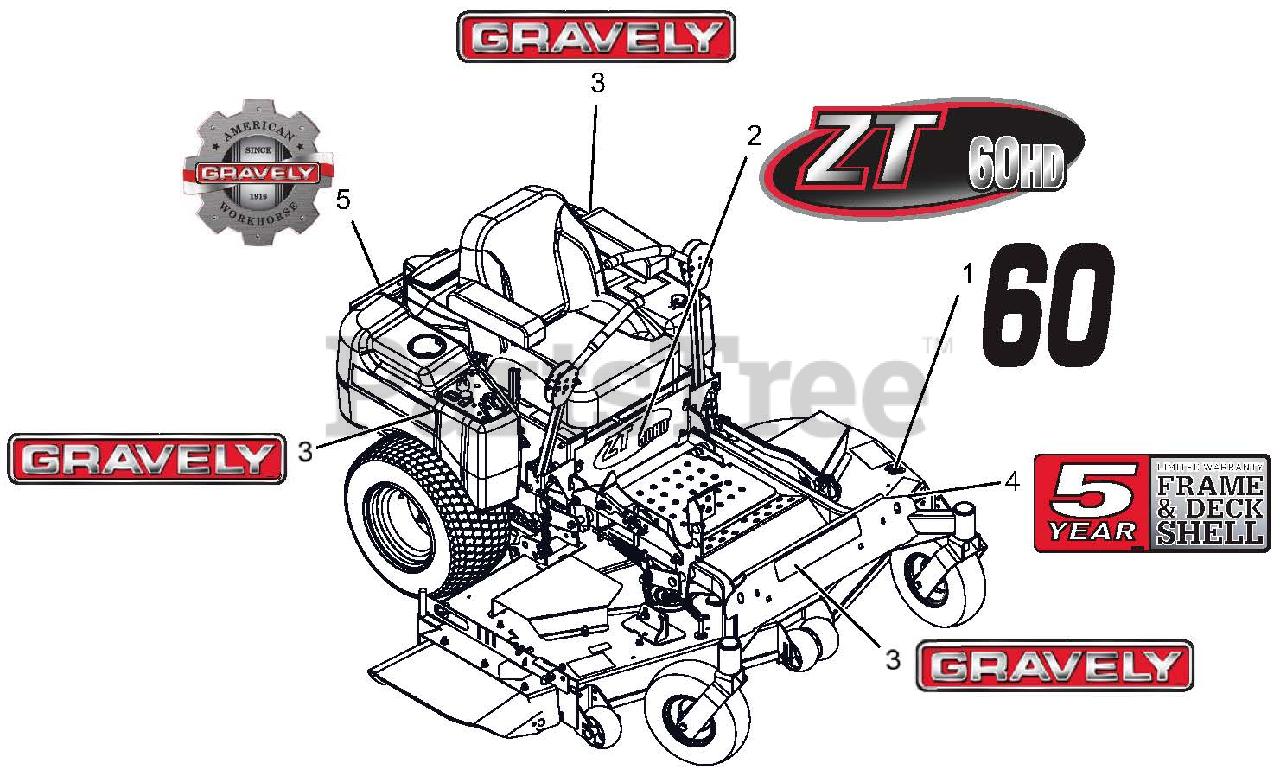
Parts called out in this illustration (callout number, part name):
1	DECAL, 60"
2	DECAL, 60HD
3	DECAL, FUEL TANK-GRAVELY
4	DECAL, DECK WARRANTY-FAB GRAVELY
5	DECAL, GRAVELY HERITAGE-SMALL
